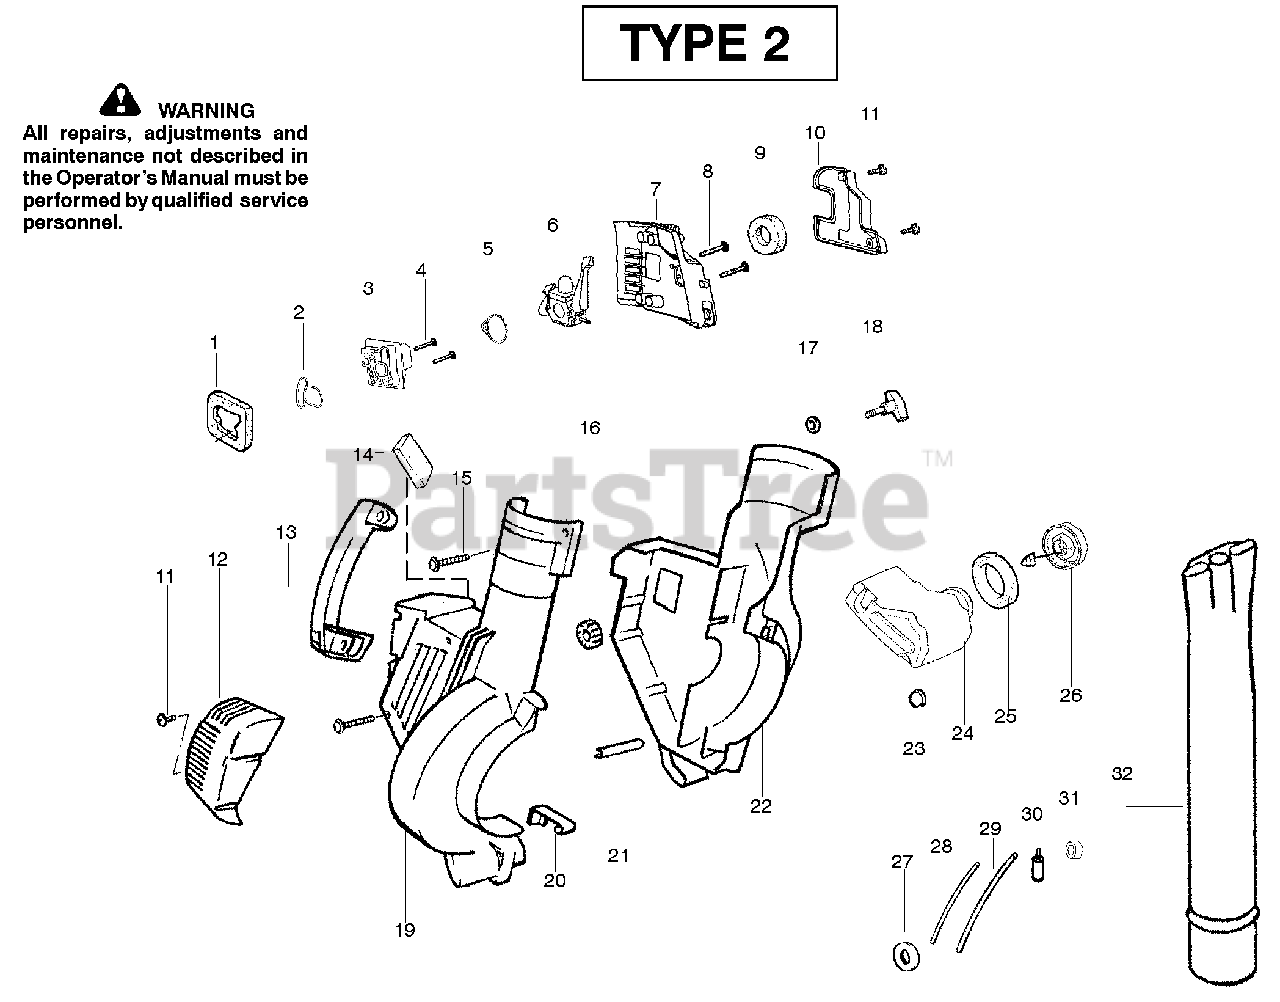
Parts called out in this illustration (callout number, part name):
1	Air Dam (kit)
2	Gasket-Adapter (kit)
3	Carburetor Adaptor
5	Gasket-Carburetor (kit)
6	Kit-Carb Ass'y. Zama-(C1Q-W11C)
6	Kit-Carb Ass'y. Walbro-(WT-606)
8	Screw-Carb.
9	Filter-Air
10	Cover-Air Filter
12	Guard-Muffler
14	Foam - 71.12mm (kit)
16	Isolator
18	Knob-Blower
19	Housing-Right
20	Spring-Cover Latch
21	Guide-Starter Rope
22	Housing-Left
23	Isolator-Crankcase
24	Assy-Fuel Tank
25	Gasket-Fuel Tank
26	Fuel Cap w/Retainer
27	Grommet-Shroud
28	Kit-Line Carb/Purge
29	Kit-Line Tank/Purge
30	Assy-Fuel Pick-up
31	Grommet-Fuel line (kit)
32	Tube-Blower
